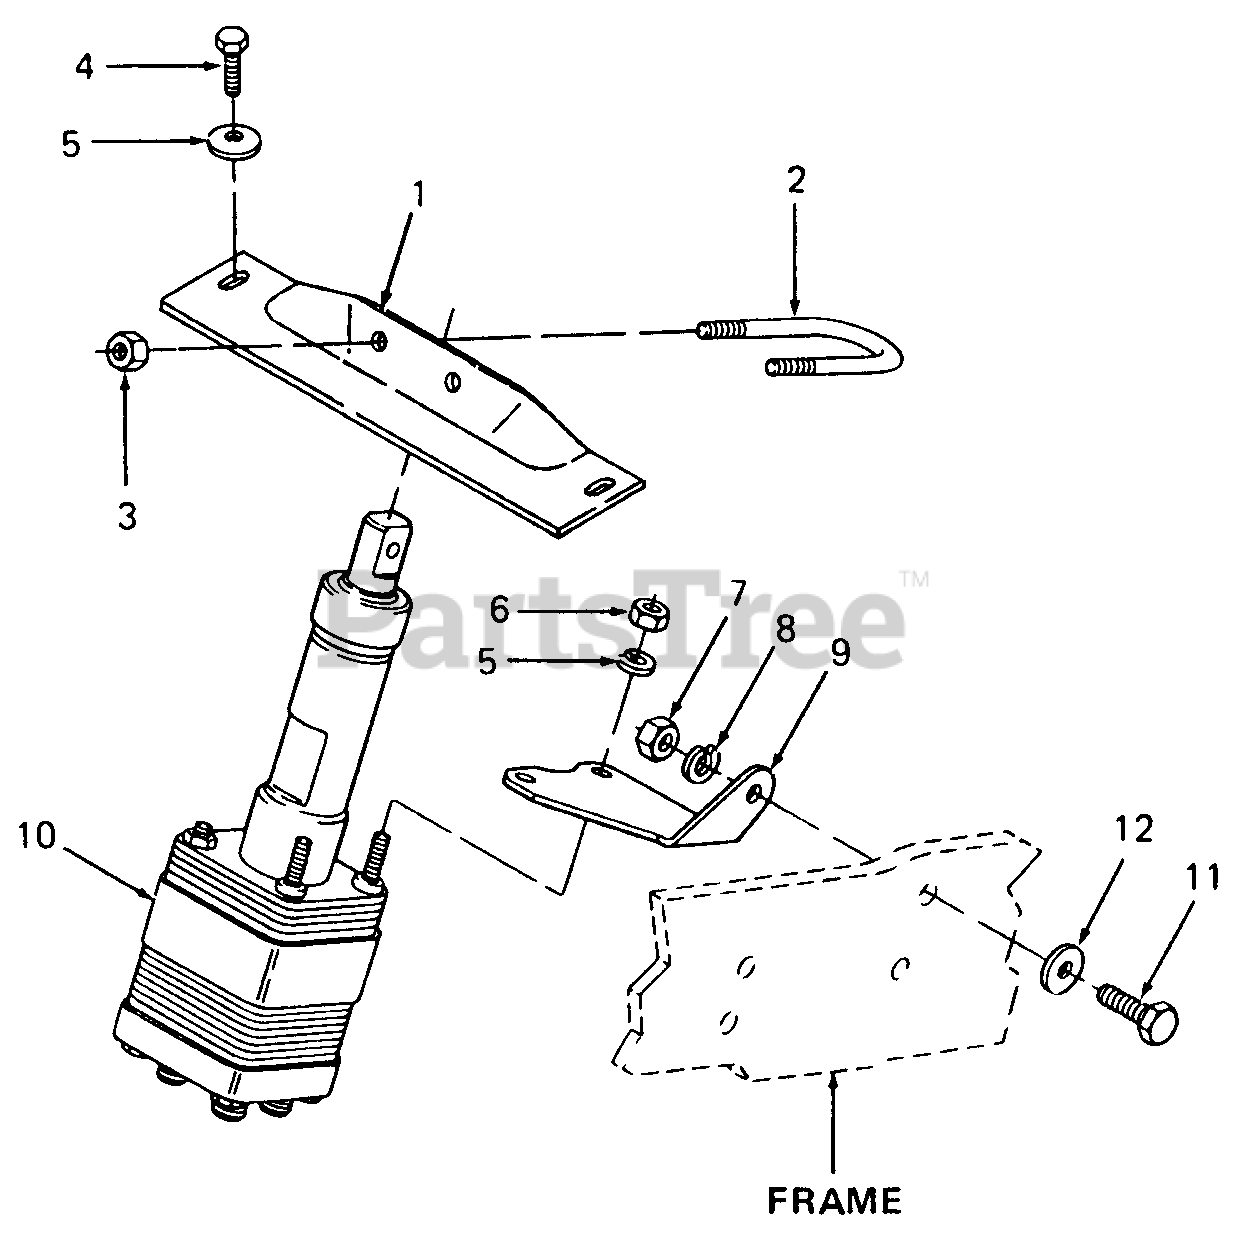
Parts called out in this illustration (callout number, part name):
1	Plate, Steering Support
3	Nut, Hex Center Lock, 5/16-24
4	Screw, Hex Cutting, 5/16-18 X .75 Lg
5	Washer, Bell, .345 X .88 X .060 Thk
6	Nut, Hex, 5/16-24 GR5
7	Nut, Hex Center Lock, 3/8-16 GR5
8	Washer, Lock, 3/8
9	Bracket, Power Steering Box Mtg
10	Power Steering Box w/Flat
11	Screw, Hex Cap, 3/8-16 X .75 Lg GR5
12	Washer, Flat, .385 X .87 X .06 Thk HDN
